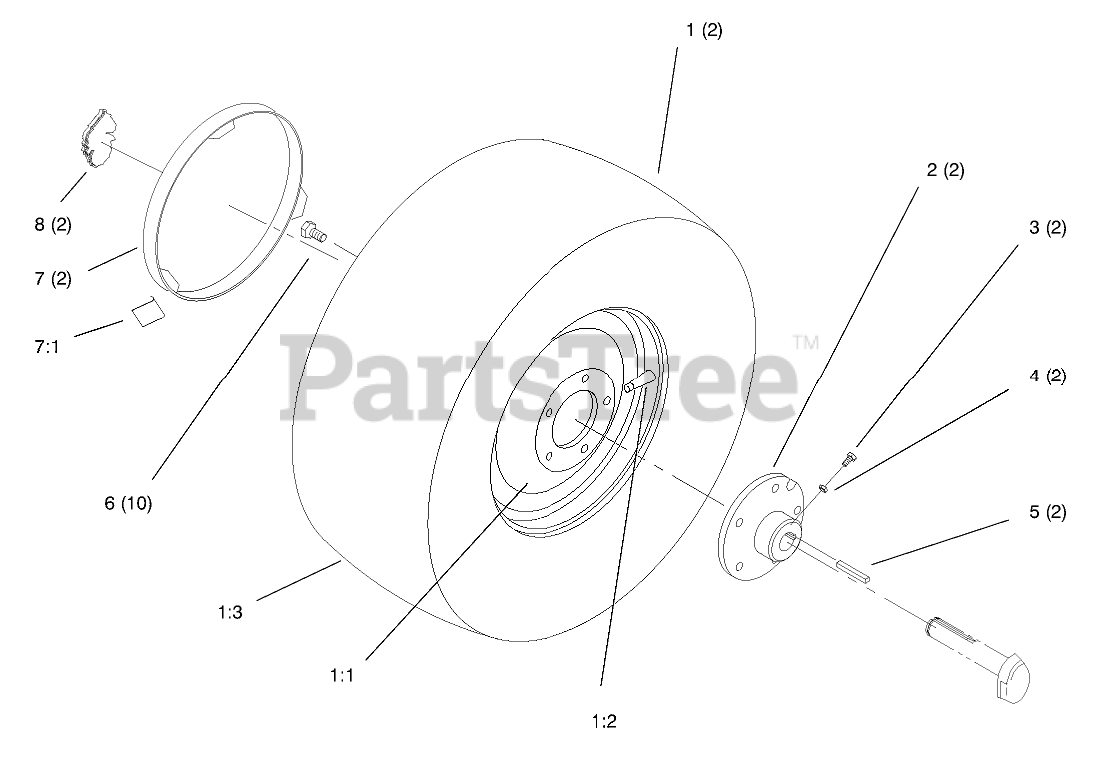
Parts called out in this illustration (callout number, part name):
1	Wheel & Tire ASM Rear
1:1	WHEEL
1:2	VALVE
1:3	TIRE 23 X 10.50-12
2	HUB-WHEEL
3	SCREW-SET, SQH
4	NUT-JAM
5	KEY-SQUARE
6	BOLT-LUG
7	HUBCAP ASM - 12", YGT (HORSEHEAD LOGO)
7	HUBCAP - 12"
8	LOGO - HORSEHEAD
